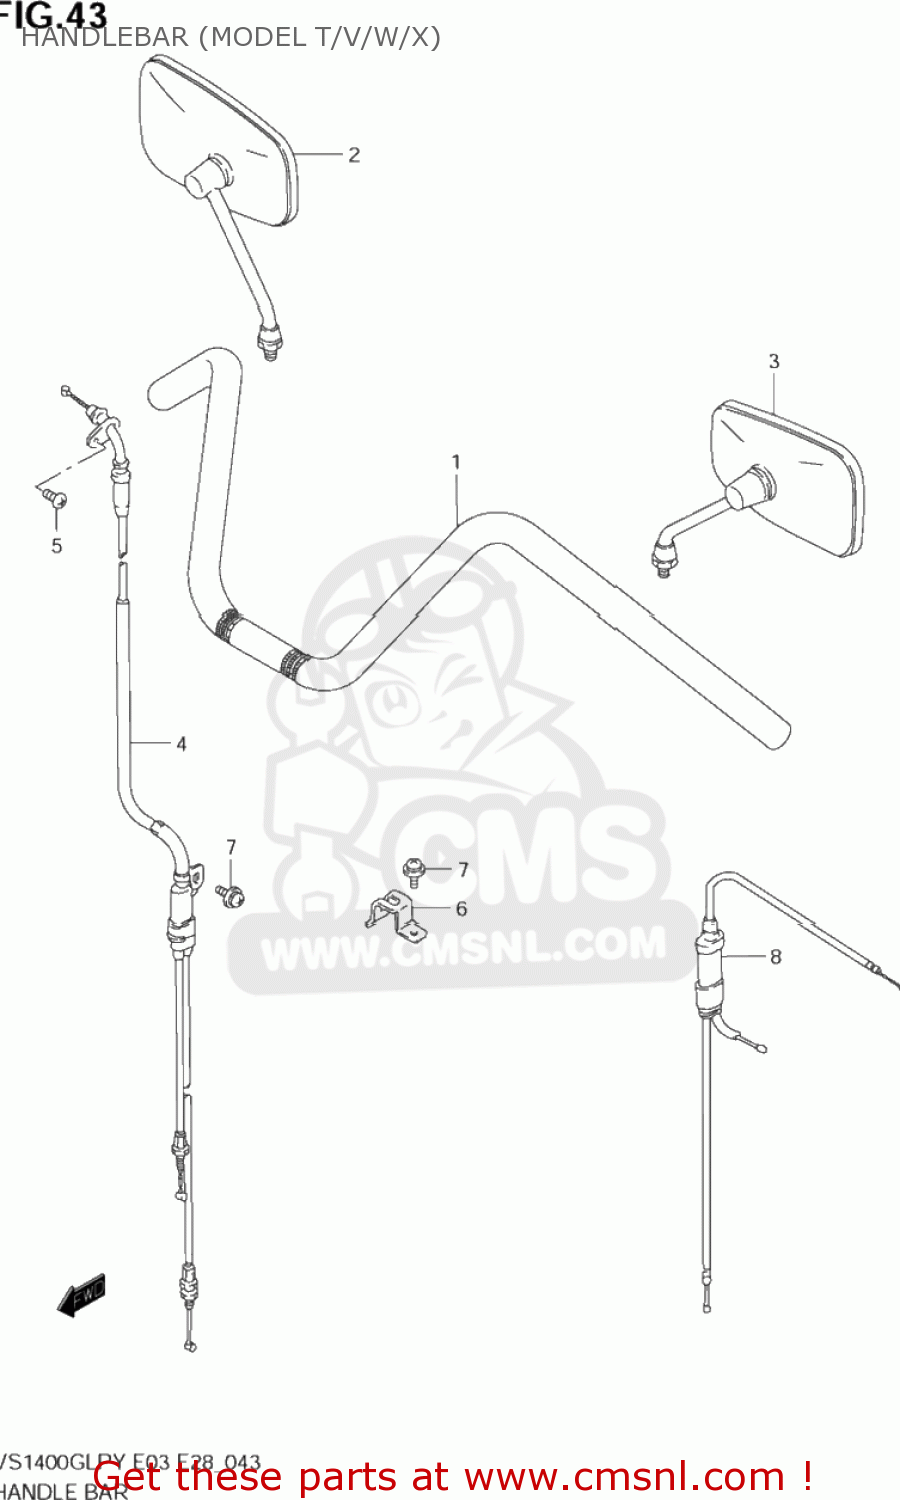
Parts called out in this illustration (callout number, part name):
1	HANDLEBAR
2	MIRROR ASSY,RR VIEW,R
3	MIRROR ASSY,RR VIEW,L
4	CABLE ASSY,THROTTLE
5	SCREW
6	CLAMP,THROTTLE CABLE CONNECTOR
7	SCREW
8	CABLE ASSEMBLY,STARTER
